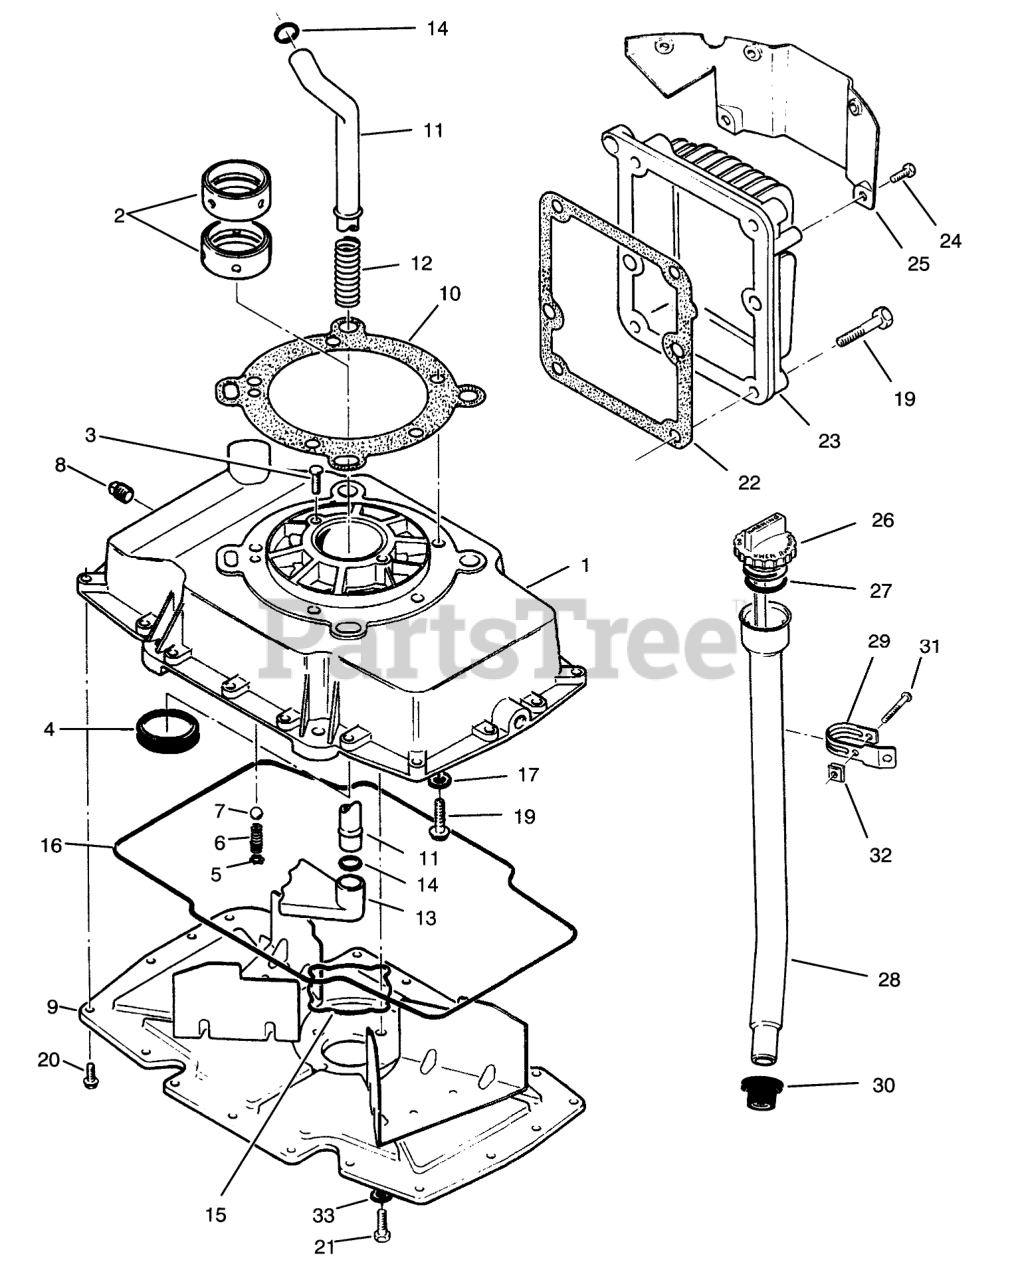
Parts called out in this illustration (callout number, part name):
1	Base-Oil (Incl. Ref. #2-7)
2	BEARING KIT (STANDARD SLEEVE)
3	Screw
4	OIL-SEAL
5	RETAINING-RING
6	SPRING
7	BALL-BEARING
8	Plug
9	OIL-BASE COVER ZINC
10	OIL-BASE GASKET
11	OIL-PICKUP TUBE
12	OIL-PICKUP SPRING
13	OIL-PICKUP CUP
14	O-RING
15	OIL-SEAL
16	OIL-SEAL
17	Washer
19	HEX-HEAD CAP SCREW
20	SCREW-HH
21	SCREW-HWH
22	Gasket
23	OIL-COOLER
24	HEX HD CAPSCREW
25	OIL-COOLER BAFFLE
26	Indicator-Oil Level (Incl. Ref. #27)
27	SEAL 0-RING
28	OIL-FILL TUBE (ZINC)
29	SUPPORT-BRKT (ZINC)
30	Seal
31	Screw
32	Nut
33	WASHER
